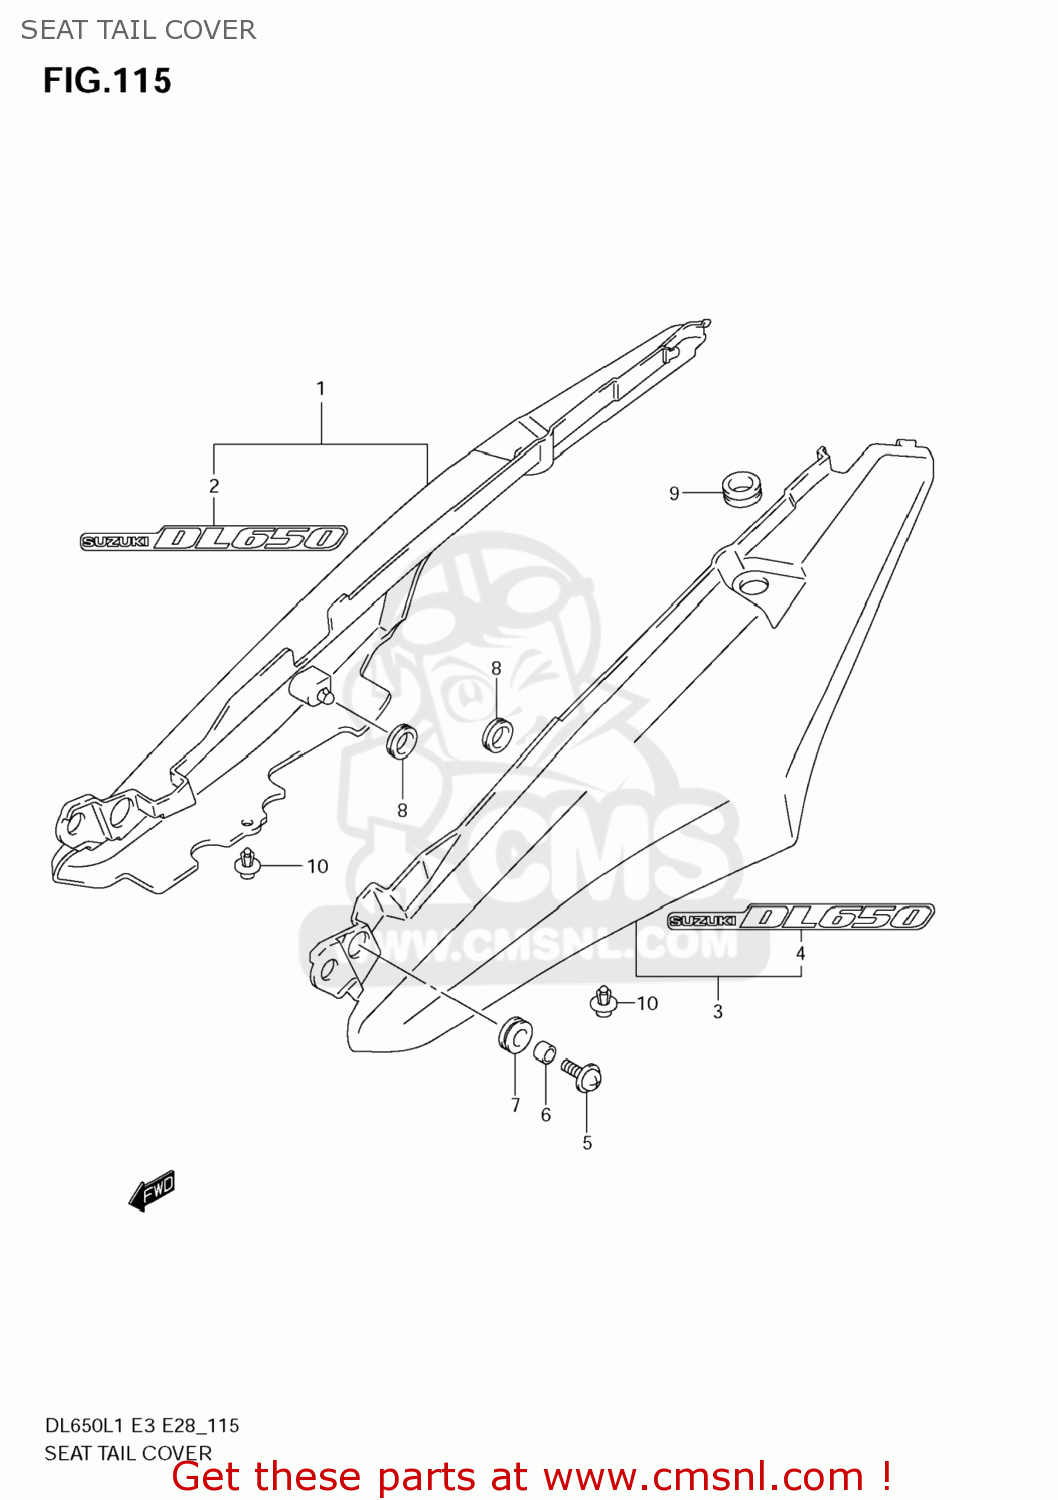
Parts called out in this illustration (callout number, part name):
1	COVER,SEAT TAIL,R(BLACK)
2	EMBLEM,SEAT TAIL COVER
3	COVER,SEAT TAIL,L(BLACK)
4	EMBLEM,SEAT TAIL COVER
5	SCREW(6X20)
6	SPACER(6.5X12X9)
7	CUSHION
8	CUSHION
9	CUSHION
10	CLIP(BLACK)
